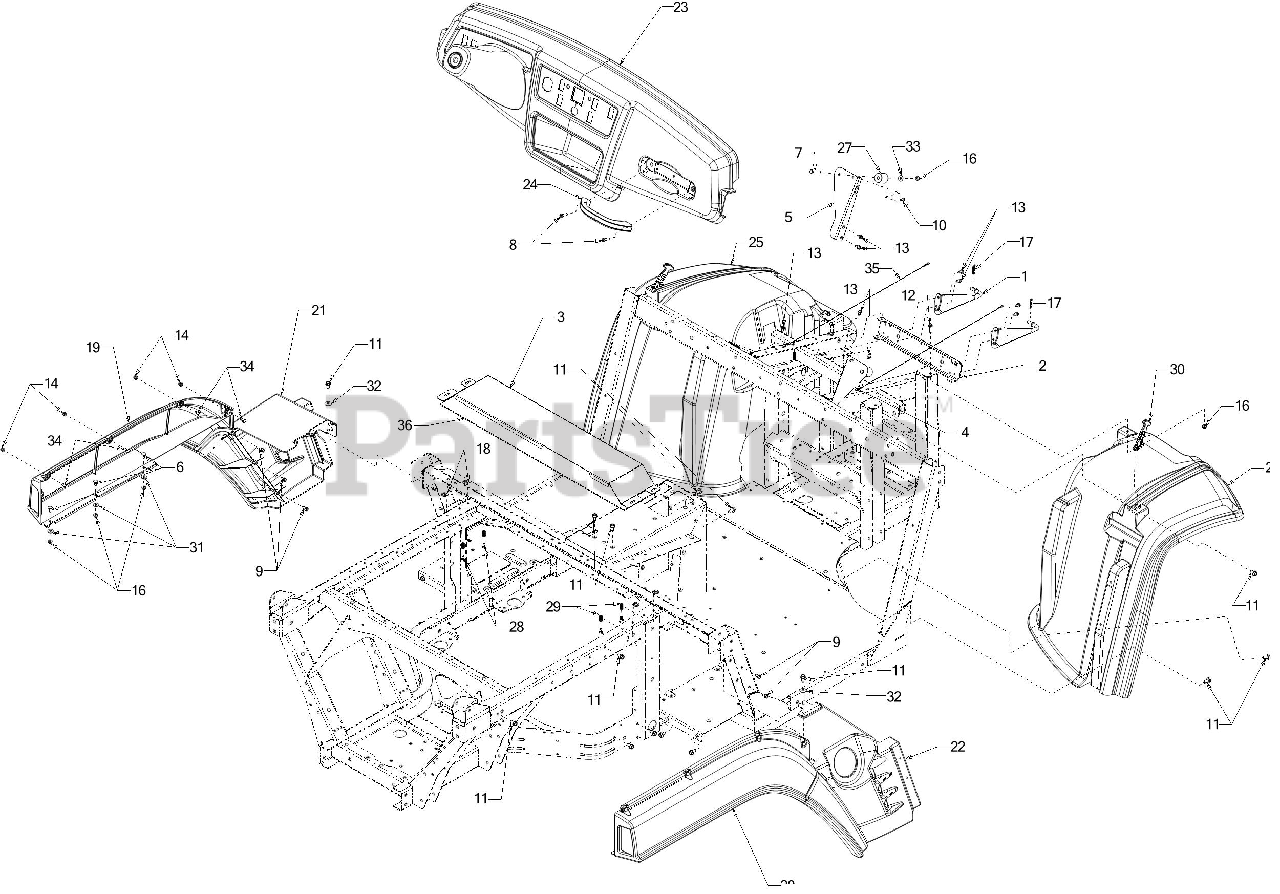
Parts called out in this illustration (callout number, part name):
1	HOOD MOUNT ROD ASSEMBLY
2	FRAME CROSS CHANNEL
4	HOOD & DASH BRACKET (RH)
5	HOOD & DASH BRACKET (LH)
6	CARRIAGE BOLT 1/4-20 x .62
7	HEX SCREW 1/4-20 x 1.75
8	MACHINE SCREW 1/4-20:1
9	HEX SCREW 1/4-15 x .50
10	HEX SCREW #12-16 x .50
11	SCREW 5/16-18 x .750
12	SCREW 1/4-20 x 1.0
13	SCREW 1/4-20 X.500
15	NYLON LOCK NUT
16	FLANGE LOCK NUT
17	INTERNAL COTTER PIN
18	1/4 TURN PANEL HANDLE
19	REAR FENDER
20	REAR FENDER
21	LOWER FENDER (LH)
22	LOWER FENDER (RH)
24	GRAB HANDLE
25	UV FENDER (LH)
26	UV FENDER (RH)
27	HOOD LATCH ROLLER
28	SPRING CLIP
29	COMPRESSION SPRING
30	HOOD STRAP
31	FLAT WASHER .28 ID x .74 OD x .063
32	BELL WASHER .337 X.867 x .057
33	FLAT WASHER .283 ID x .749 x .030
34	SHOULDER SCREW 1/4-20
35	HOOD CABLE
36	INSULATION
